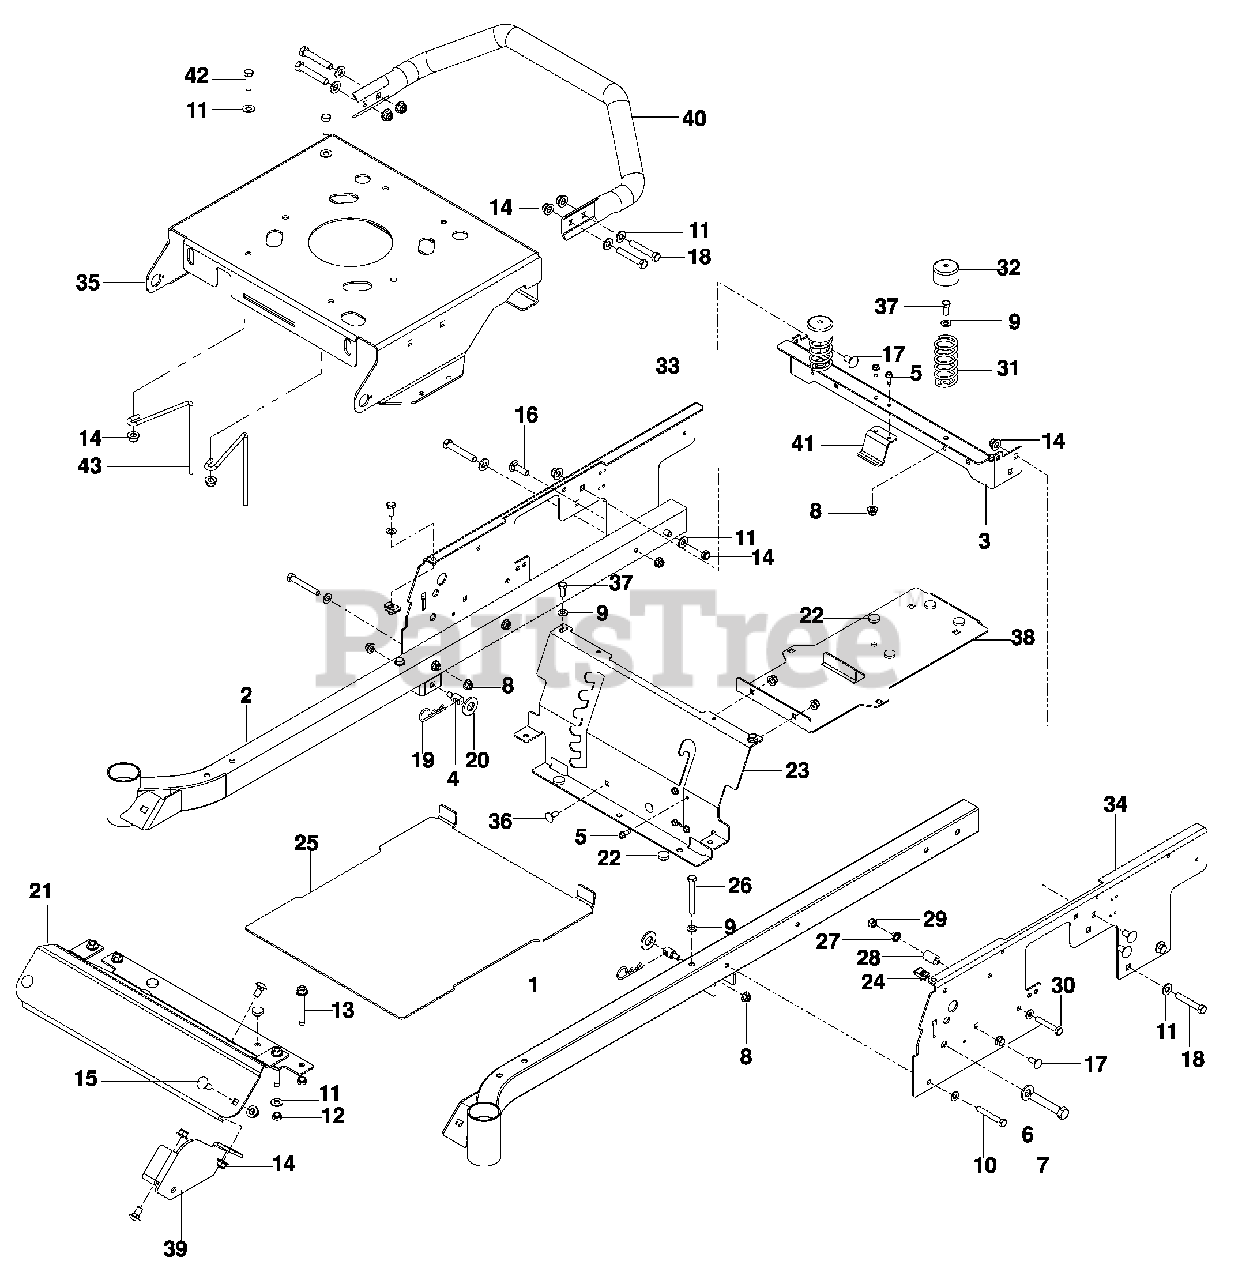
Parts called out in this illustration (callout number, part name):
1	FRAME TUBE, LH
2	FRAME TUBE, RH
3	SUPPORT, REAR SEAT
4	STUD w/ ANTI-ROTATE
5	SCREW ¼-20 x 5/8 SLF TAP
6	WASHER ½ SAE
7	BOLT, HEX HD ½-13 x 2¾
8	NUT 5/16-18 FLANGE NYLOC
9	WASHER 5/16 SAE FLAT
10	BOLT, HEX HD 5/16-18 x 2¼
11	WASHER 3/8 SAE FLT
12	NUT 3/8-16 HEX JAM NYLOC
13	BOLT 3/8-16 x 25/8 THD FRM
14	NUT 3/8-16 FLANGE NYLOC
15	BOLT, RD HD 3/8-16 x 1
16	BOLT, RD HD 3/8-16 x 1¼
17	BOLT, RD HD 3/8-16 x ¾
18	BOLT, HEX HD 3/8-16 x 2¼
20	WASHER 5/8 SAE FLT
22	GROMMET,BUMPER
23	PANEL, SEAT SUPPORT
24	U TYPE RETAINER
25	FOOT PLATE
26	BOLT, HEX HD 5/16-18 x 2¾
27	NUT 5/16-18 HEX WHIZLK
29	NUT 5/16-18 HEX NYLOC
30	BOLT, HEX HD 5/16-18 x 2
31	SPRING, SEAT
32	CAP, SPRING
35	PLATE, ENGINE
36	BOLT, RD HD 5/16-18 x ¾
37	BOLT, HEX HD 5/16-18 x ¾
38	SUPPORT, TANK
39	BRACKET, FRONT DECK
40	GUARD, REAR
41	BRACKET, FUEL TANK
42	BOLT, HEX HD 3/8-16 x 1¼
43	GUIDE, BELT
